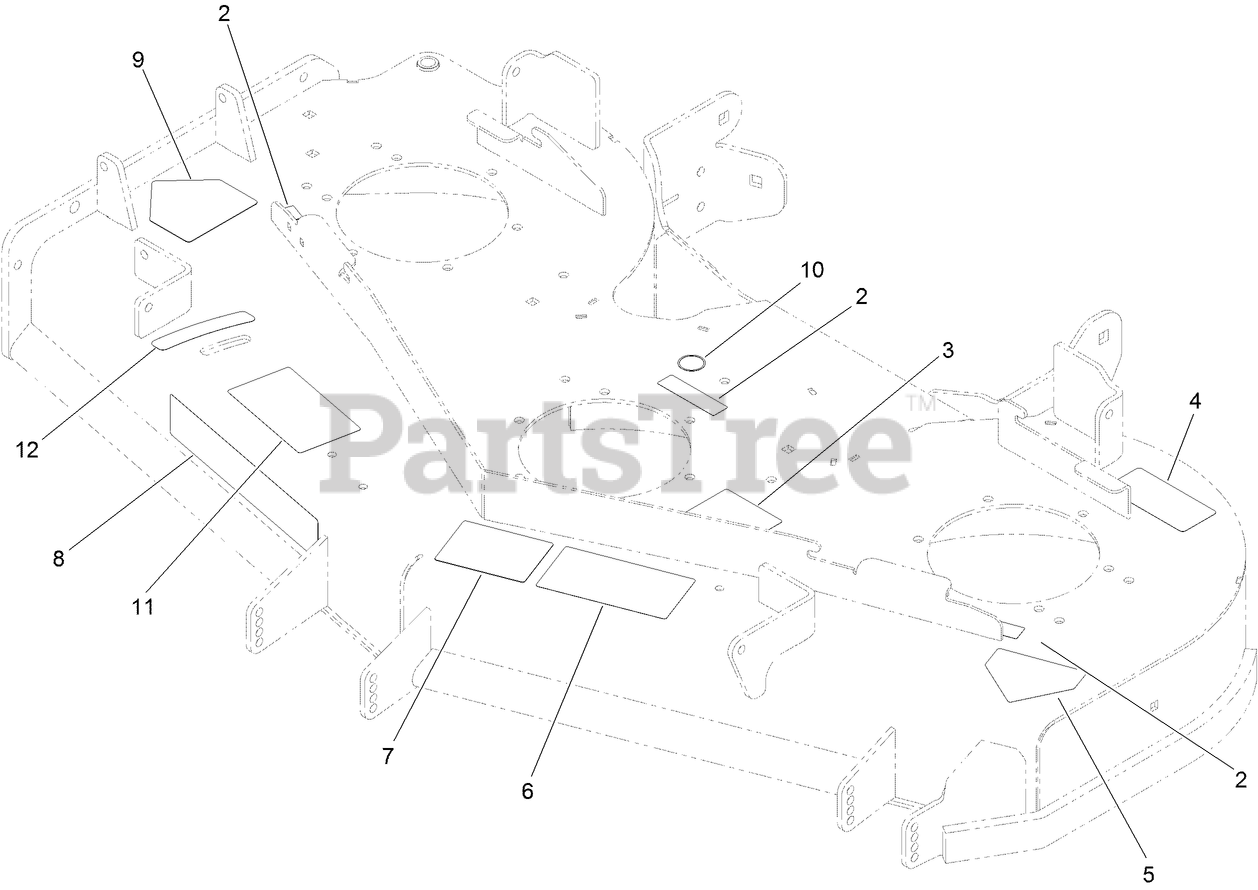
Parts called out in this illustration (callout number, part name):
2	DECAL-COVER, MISSING
3	DECAL-ROUTING, DECK BELT
4	DECAL-TORQUE
5	DECAL-DANGER
6	DECAL-DANGER, THROWN OBJECT
7	DECAL-SCALP, ANTI
9	DECAL-DANGER
10	DECAL-GREASE
11	DECAL-ADJUSTMENT, BAFFLE
12	DECAL-SETTING, BAFFLE
